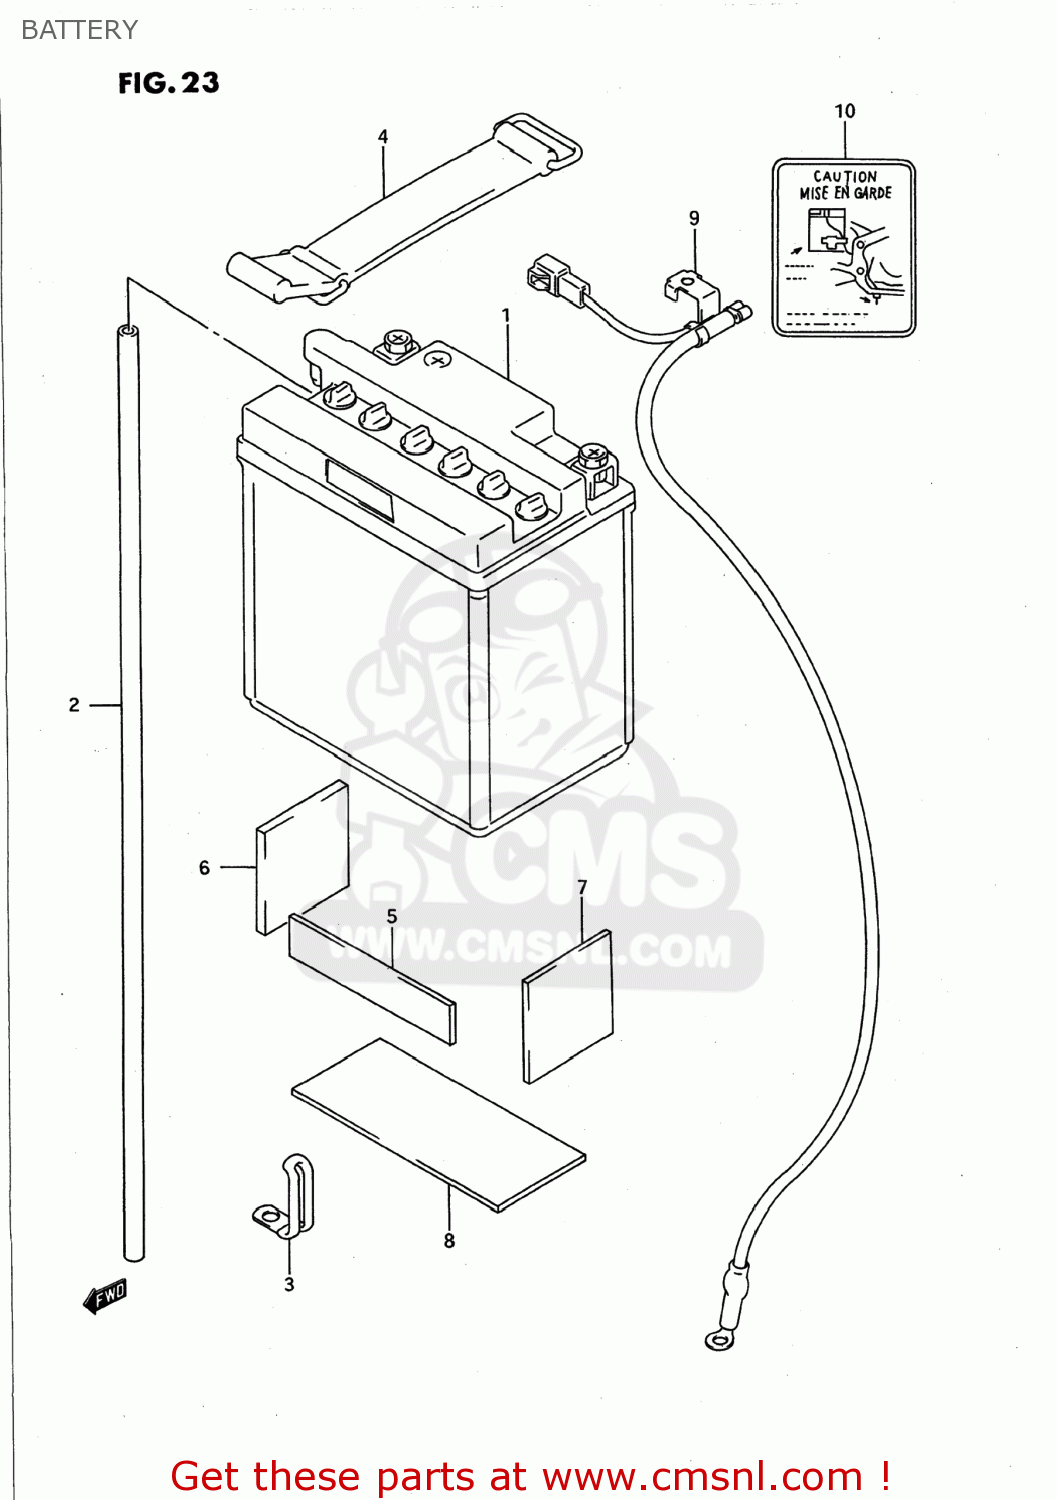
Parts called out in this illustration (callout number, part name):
1	BATTERY ASSEMBLY (12V)
2	HOSE,BATTERY EXHAUST
3	CLAMP(L:35)
4	BAND
5	PROTECTOR(170X95X3.0)
6	PROTECTOR(50X50X5)
7	PROTECTOR(170X95X3.0)
8	PROTECTOR(170X95X3.0)
9	WIRE,BATTERY MINUS LEAD
10	PLATE,BATTERY CAUTION
